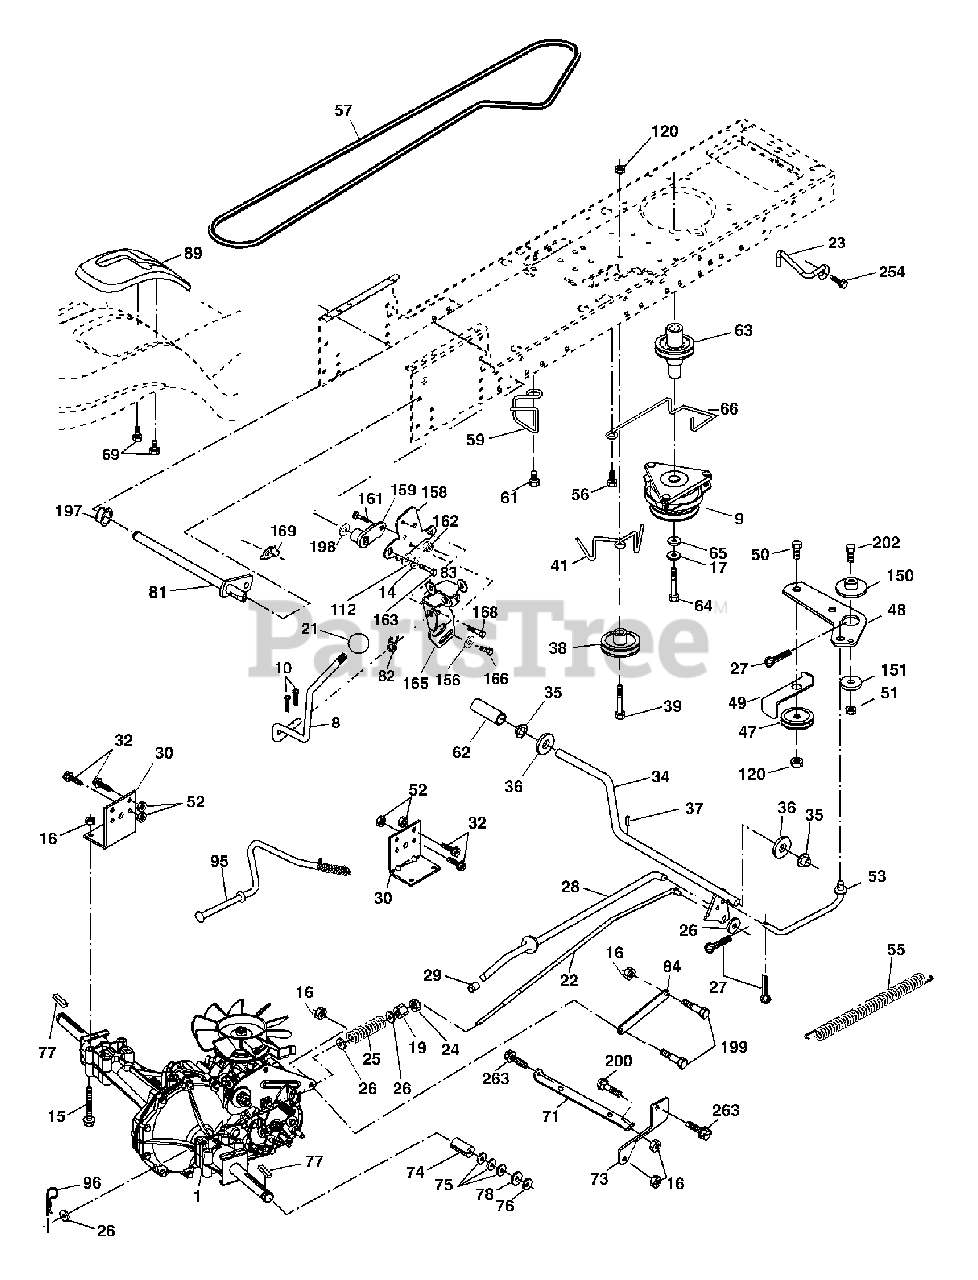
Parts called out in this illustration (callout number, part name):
9	Clutch Ogura
10	Pin Cotter 1/8 x 1 CAD
14	Washer Lock Hvy Helical
15	Bolt, Hex FLGHD 5/16-18 Gr. 5
16	Nut Lock Hex W/Ins 5/16-18 unc
19	Nut Lock Hex W/Wsh 3/8-16 unc
22	Rod, Brake Hydro
23	Bracket Anti Rotation
24	Nut
25	Spring, Brake Rod
26	Washer
27	Pin Cotter 1/8 x 3/4 CAD.
28	Rod, Parking Brake
29	Cap, Parking Brake
30	Bracket, Transaxle
32	Bolt Hex Hd 5/16-18 unc x 3/4
34	Shaft, Foot Pedal
35	Bearing, Nylon
37	Pin, Roll
38	Pulley, Composite
39	Bolt Rdhd 3/8-16 unc x 2-3/4 Gr. 5
41	Keeper, Belt Idler
47	Pulley, Idler, V-Groove
48	Bellcrank Clutch Grnd Drv STL
49	Retainer, Belt
50	Bolt Carr Sh 3/8-16 x 1-1/2 Gr. 5
51	Nut Crownlock 3/8-16 unc
52	Nut Crownlock 5/16-18 unc
53	Link, Clutch
55	Spring, Return, Clutch
56	Screw 3/8-16 x 1-1/4
57	V-Belt, Ground Drive
59	Keeper, Center Span
61	Screw 3/8-16 x .875
62	Cover, Pedal
63	Pulley, Engine
64	Bolt Hex 7/16-20 x 4 x Gr. 5-1.5 Thr
65	Washer
66	Keeper Belt Engine
69	Screw Hex Wsh Hi-Lo 1/4 x 1/2 unc
71	Strap Torque Lh Hydro
73	Strap Torque Rh Hydro
74	Spacer, Axle
75	Washer 25/32 x 1-1/4 x 16 Ga.
77	Key, Square
78	Washer 25132 x 1-5/8 x 16 Ga.
81	Shaft Asm. Cross Hydro
82	Spring Torsion T/A
83	Washer 17/32 x 3/4 x 16 Ga.
84	Link Transaxle
89	Console, Shift
95	Control Asm Bypass Hydro
96	Retainer Spring 1" Zinc/Cad
112	Washer 9/32 x 3/4 x 10 Ga.
120	Nut Lock Flg 3/8-16 unc
150	Spacer Retainer
151	Washer 13/32 x 2 x 10 Ga.
156	Washer Srrted 5/16 ID x 1.125
158	Bracket Shift Mount
159	Hub Shift
161	Bolt Rdhd Sqnk 1/4-20 x 3/4 Gr. 5
162	Nut Crownlock 1/4-20 unc
163	Bolt Hex Fin 1/4-20 unc x 1 Gr. 5
165	Bracket Pivot Lever
166	Screw 5/16-18 x 5/8
168	Bolt Shoulder 5/16-18 x .561
169	Plate Fastening Lt
197	Nyliner Snap-In 5/8" ID
198	Washer Nyl 7/8 ID x .105
199	Bolt Shoulder 5/16-18 unc
200	Bolt Rdhd Sqnk 5/16-18 unc x 1
202	Bolt Carr Sh 3/8-16 x 1-3/4 Gr. 5
254	Screw 3/8-16 x 1
263	Thdrol Screw 3/8-16 x 3/4
